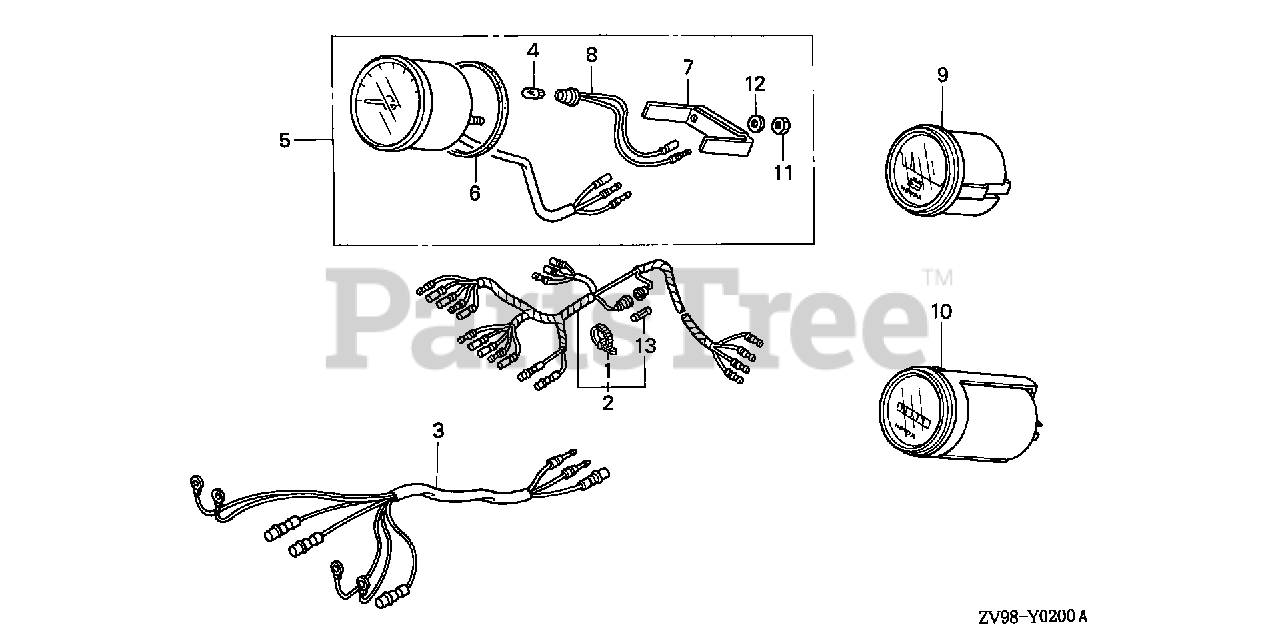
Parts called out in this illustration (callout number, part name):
1	BAND B1, WIRE
2	HARNESS ASSY., METER (A)
3	HARNESS ASSY., METER (B)
4	BULB, WEDGE BASE (T10) (12V 1.7W) (STANLEY)
5	TACHOMETER ASSY.
6	GASKET
7	BRACKET
8	SOCKET
9	METER ASSY., VOLT (NOT AVAILABLE)
10	METER ASSY., HOUR L.C.D.
11	NUT, HEX. (5MM)
12	WASHER, SPRING (5MM)
13	FUSE A (10A)
